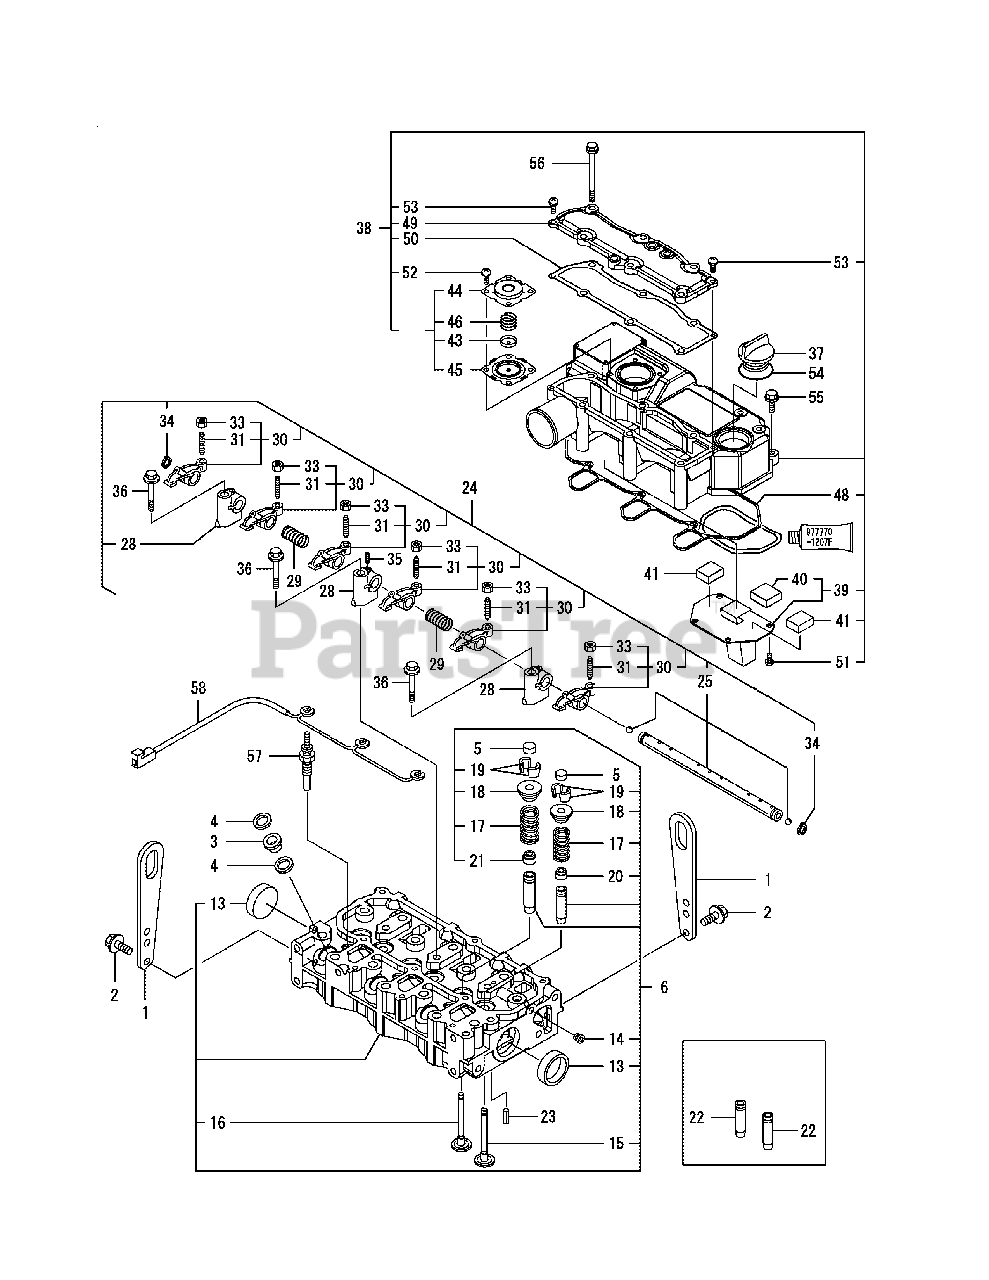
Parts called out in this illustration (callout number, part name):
1	Lifter, Engine
2	Bolt, M 8 x 16 Plated
3	Protector, Nozzle
4	Gasket, Nozzle
6	Head Assembly, Cylinder
14	Plug Pt, 1/16, Screw
16	Valve, Exhaust
18	Retainer, Spring
20	Seal, Valve Stem
21	Seal, Valve Stem
23	Spring Pin, 6 x 12
24	Support Assembly, Arm
25	Shaft Assembly, Rocker
28	Support, Rocker Arm
30	Arm Assembly, Rocker
33	Nut, M8 x P1.0
35	Screw, M 5 x 16
36	Bolt, M8 x 40 Plated
38	Bonnet Assembly, Head
40	Baffle, Breather
41	Baffle, Breather
43	Plate, Diaphragm
44	Cover, Diaphragm
46	Spring, Diaphragm
48	Gasket, Bonnet
50	Gasket, Bonnet Cover
51	Screw, 5 x 10, Tapping
52	Screw, 5 x 10, Tapping
54	O-Ring, 1A P-32.0
55	Bolt, M 6 x 20 Plated
56	Bolt, M 6 x 75 Plated
57	Plug, Glow
58	Connector, Glow Plug
